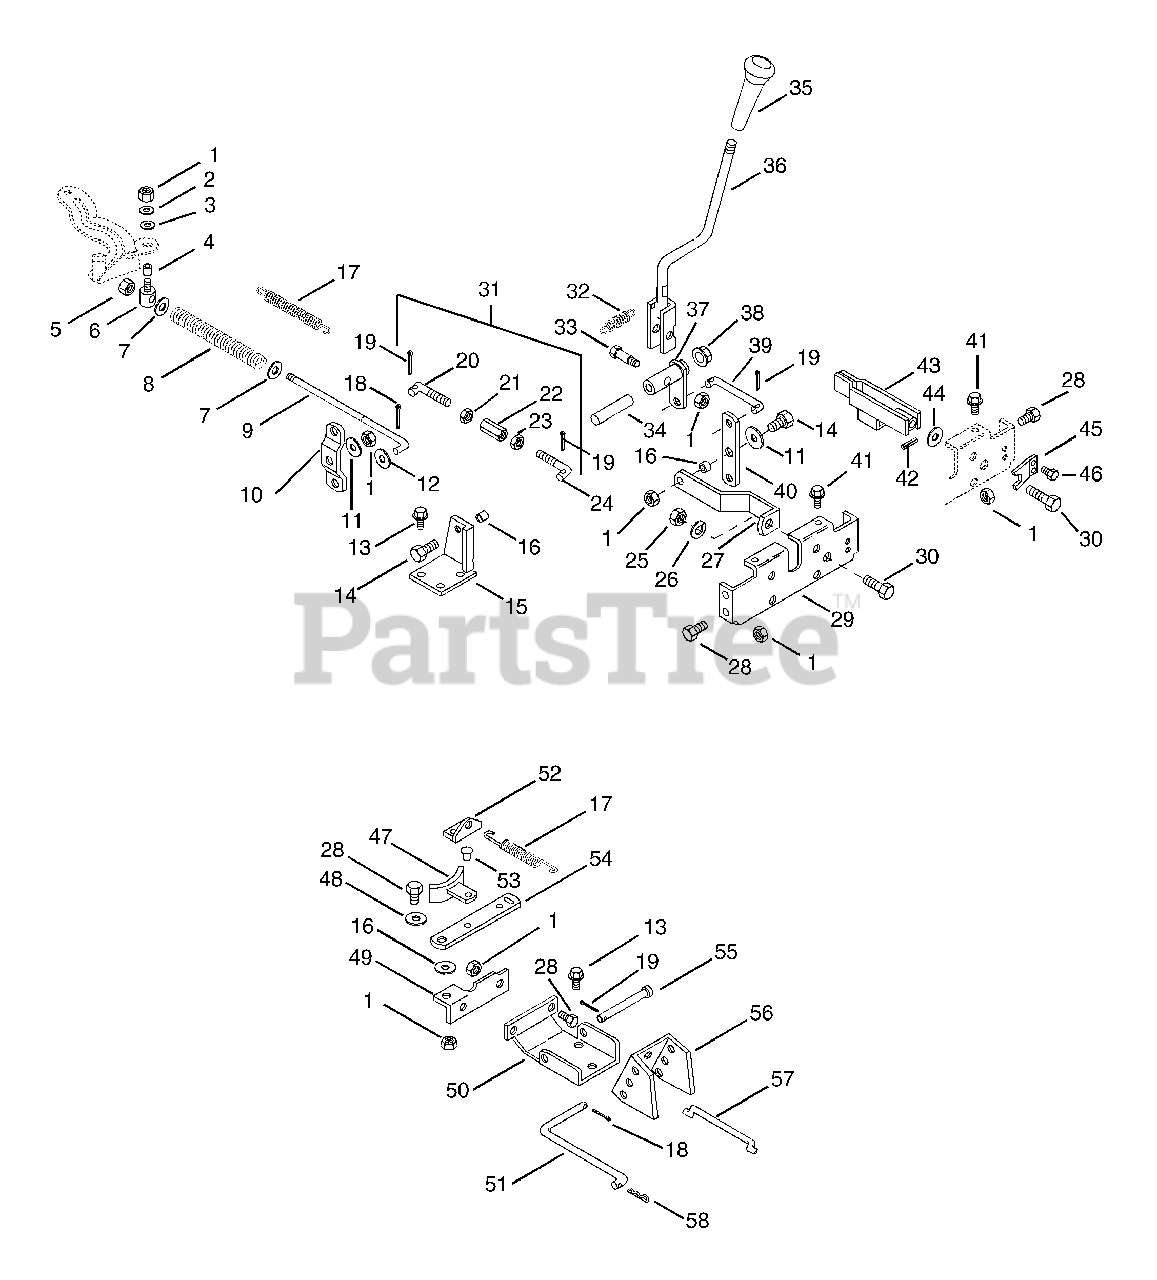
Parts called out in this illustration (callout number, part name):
1	@NUT-LK-CTR .31-18 YWZC
2	WSHR-FL-STL .323X.625X.062 YWZ
3	WAVE WASHER .531X.781X.125FH
4	SPACER BUSHING .5 X .32 X .21
5	@NUT-LK-CTR .38-16 YWZC
6	ROD PIVOT
7	@WSHR-FL-STL.38X.875X.083 YWZC
8	SG-COMP .148X.68X6.5 WLD 90
9	CLUTCH ROD
10	ARM
11	WSHR-FL-STL .328X.875X.062YWZC
12	@WSHR-FL-STL.344X.688X.065YWZC
13	@SCR-TAP .31-18X.50 HWH TR YWZ
14	BOLT-HEX.31-18X.875 YWZC GR5
15	DECK PIVOT BRACKET
16	SPACER BUSHING .5 X .32 X .163
17	SG-TENS .072X.51X5.31 WLD 25
18	@PIN-CTR .12X.75 EXTPRSQCT YWZ
19	@PIN-CTR .09X.75 EXTPRSQCT YWZ
20	CLUTCH ROD RH
21	@NUT-HEX .38-16 YWZC
22	NUT-CUPLG RH & LH THD .37-16PL
23	NUT-LH-THD .375-16 GR2 YWZC
24	CLUTCH ROD LH
25	@NUT-HEX .50-13 YWZC
26	WSHR-LK .500X.151 HVY YWZC
27	FRONT ANCHOR
28	@BLT-HEX .31-18X.75 GR5 YWZC
29	MOWER ADJUSTMENT BRACKET
30	CAP SCREW
30	@BLT-HEX .50-13X1.25 GR5 YWZC
31	CLUTCH ROD SERVICE ASSY
32	SG-TENS .092X.69X1.75 WLD 54
33	SHOULDER BOLT .436 X .912
36	MOWER CLUTCH LEVER
37	CLUTCH ARM
38	FLANGE BUSHING
39	LINK
40	CLUTCH LINK
41	@SCR-TAP .25-20X.50 HWH TR YWZ
42	PIN-ROLL .188X1.00
43	ADJUSTMENT YOKE
44	WSHR-FL-STL .505X1.00X.062YWZC
45	LOCK SPRING
46	@SCR-TAP 10-24X.375 HWH YZ TR
47	BLADE BRAKE
48	WSHR-FL-STL .328X1.0X.094 YWZC
49	BRAKE BRACKET
50	PIVOT BRACKET
51	MOWER ENGAGEMENT LINK
52	BRAKE CLIP
53	RVT .25X.50 RH ST
54	MOWER BRAKE LEVER
55	PIN-CLEV .309X3.50 SP
56	MOWER ENGAGING ARM
57	MOWER BRAKE LINK
57	MOWER BRAKE LINK SERVICE ASSY
58	PIN-HAIR INT .08X.38X1.42 YWZC
